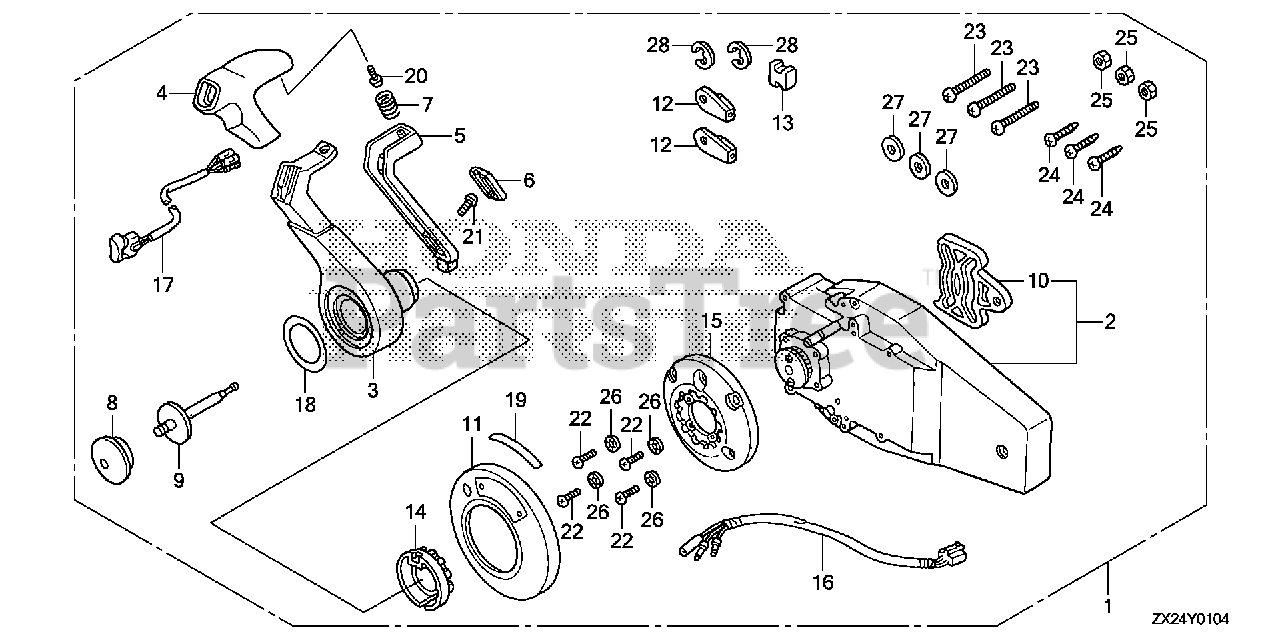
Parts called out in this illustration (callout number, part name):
1	BOX KIT, REMOTE CONTROL (FLUSH MOUNT)(R)
2	HOUSING ASSY., R. (INNER) (FLUSH MOUNT)
3	HANDLE, REMOTE CONTROL
4	COVER, GRIP
5	ARM, NEUTRAL LOCK
6	COVER, LOCK ARM
7	SPRING, NEUTRAL LOCK ARM
8	BUTTON, THROTTLE
9	SHAFT, THROTTLE BUTTON
10	PLATE, DWELL
11	COVER ASSY.
12	TERMINAL, CABLE
13	SPACER, CABLE CLAMP
14	HOLDER, NEUTRAL LOCK
15	BASE
16	SUB-HARNESS ASSY., POWER TRIM-TILT (C)
17	SWITCH ASSY., POWER TRIM-TILT (C)
18	MARK, HANDLE FLUSH MOUNT
19	MARK, FLUSH MOUNT
20	SCREW, PAN (5X16)
21	SCREW, TRUSS (4X12)
22	SCREW, PAN (5X30)
23	SCREW, PAN (6X35)
24	SCREW, TAPPING (6X30)
25	NUT, HEX. (6MM)
26	WASHER, LOCK (5MM)
27	WASHER, PLAIN (6MM)
28	E-RING (6MM)
